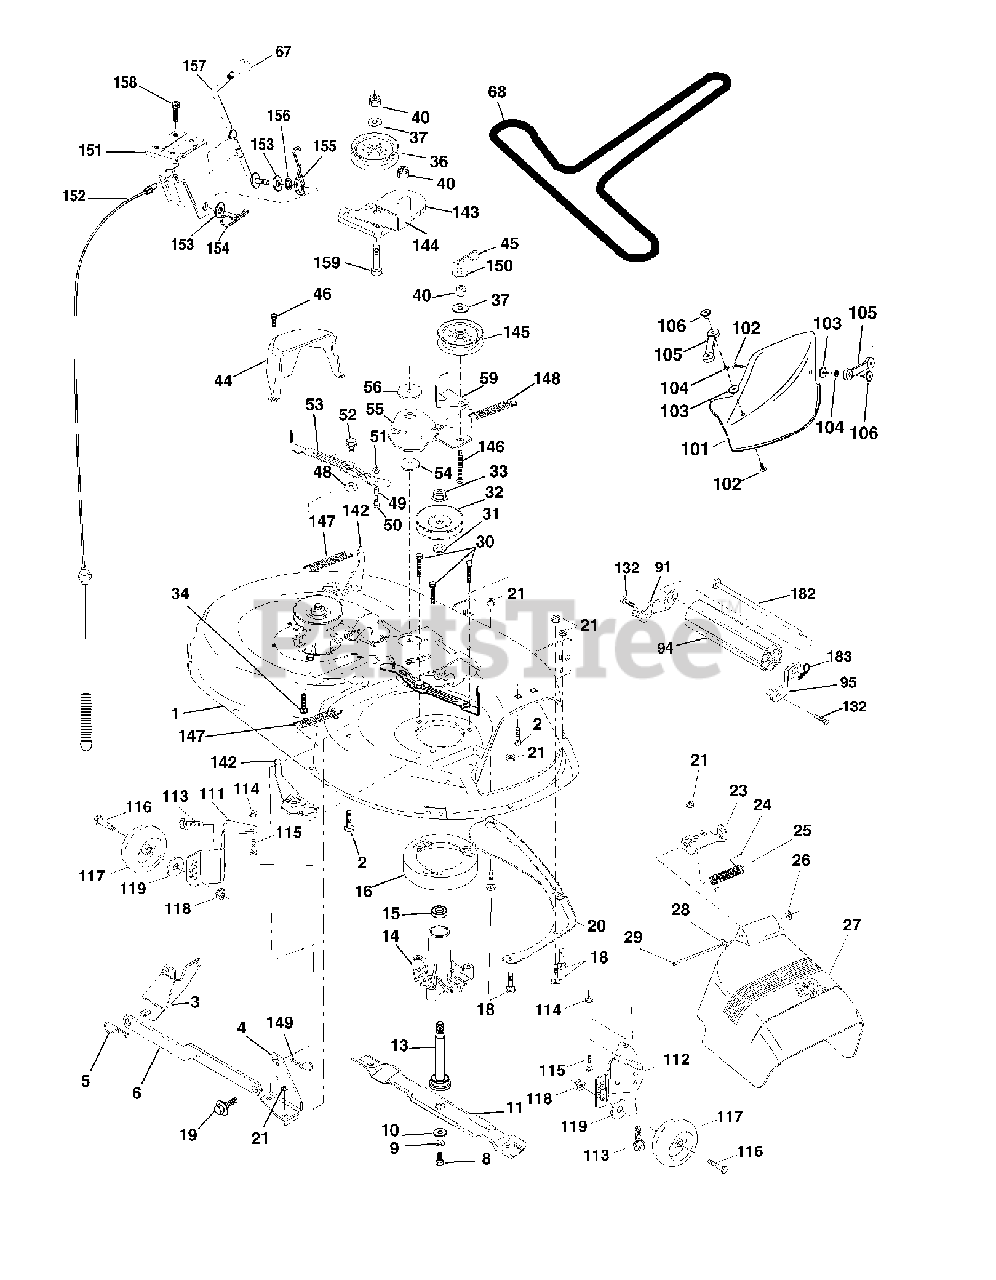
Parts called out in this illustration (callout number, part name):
2	BOLT
3	BRKT ASM SWAY BAR
4	BRACKET SWAY BAR 42" DECK
5	RETAINER-SPRNG RB
6	BAR SWAY DECK
8	BLADE BOLT
10	WASHER.BLADE
11	BLADE.42".MULCH
13	SHAFT ASM VENT
14	HSG MANDREL
16	STRIPPER.MANDREL.ROUND.BLACK
18	BOLT
19	BOLT SHD 5/16-18
20	BAFFLE.VORTEX
21	LOCKNUT
23	BRKT, DEFL. MOWER
24	CAP-SLEEVE LT
25	DEFLECTOR SPRG T
26	NUT PUSH M
27	SHIELD DEFLECTOR
28	WASHER
29	ROD.HINGE
30	SCREW, WASHER HEAD
31	WASHER
32	PULLEY MANDREL
33	Flange Lock Nut, 9/16-18 Thread Nyloc ZD
34	BOLT
36	PULLEY.IDLER.FLAT
40	LOCKNUT
44	MANDREL GUARD LH
46	SCREW.1/4-20X5/8
49	ROLLER ASM CAM FOLLOWER
50	BOLT
52	BOLT, SHOULDER LT
55	ARM IDLER 42" MOWER LT/YT
59	GUARD TUV IDLER
67	KNOB T (3/8 HOLE)
68	BELT V SECONDARY
91	BRACKET ASM NOSEROLLER LH
94	MANUAL, OPERATOR
95	BRACKET ASM NOSEROLLER RH
101	COVER MULCH 42"
104	LOCKWASHER
105	LATCH ASSY
106	WELDNUT
113	SCREW.3/8-16X.625
115	BOLT
116	BOLT M
117	WHEEL.GAUGE.STANDARD
118	LOCKNUT
119	WASHER
142	ARM SPRING BRAKE MOWER
143	BRACKET, ARM IDLER
144	KEEPER BELT 42" CLUTCH
145	PULLEY.IDLER.FLAT.PLATED
146	BOLT CARRIAGE IDLER
147	SPRING EXTENSION
148	IDLER RETURN SPRING
149	SPRING.RETAINER.YELLOW.ZINC
150	WASHER PM
151	BRACKET.CLUTCH.CABLE
152	Clutch Cable Kit
153	WASHER FLAT 3/8"
154	SPRING RETAINER
155	SPRING RETENTION LEVER
156	SPACER CLUTCH CABLE
157	ROD CLUTCH CABLE 3/8"
159	BOLT
182	ROD ROLLER NOSE STANDARD
183	SPRING RETAINER
